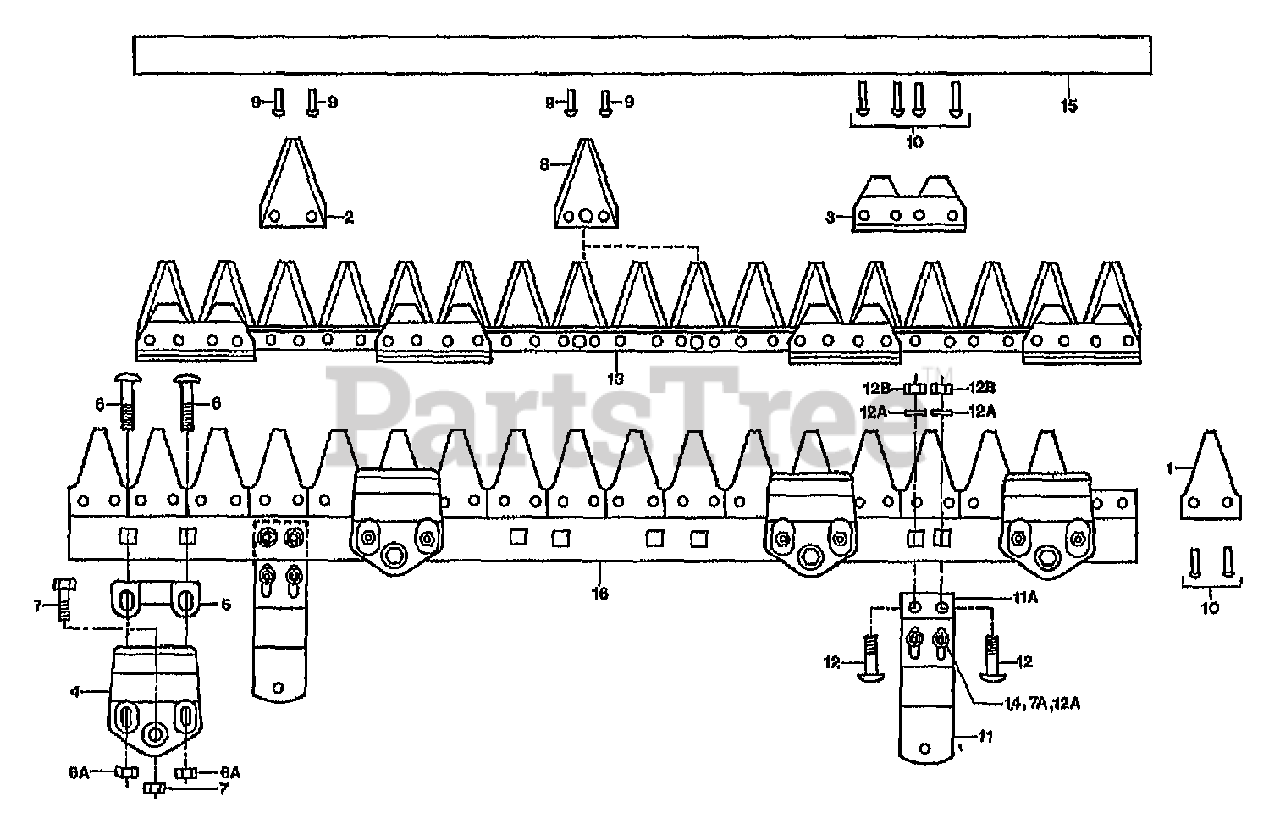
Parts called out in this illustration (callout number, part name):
1	LEDGER SECTION
2	BAR-CUTTER 2 HOLE BLADE SECTIO
3	PLATE-WEAR
4	CLIP-BLADE GUIDE
5	PLATE
6	SCR-CARR M8 X 40
7	SCR-HH M8 X 30
7A	NUT-M8 BRAKE
8	BLADE-SECTIONS 3 HOLES
9	RIVETS-CS90 5.3 X 14
11	BOTTOM HALF - HEIGHT ADJUSTER
11A	TOP HALF - HEIGHT ADJUSTER
12	SCR-CARR M8X30MM SQNK
12A	WASHER-FLAT 5/16 SAE
12B	NUT-NYLOC M8
13	ASSM-34" BLADE T/B SICKLEBAR
14	BOLT-U M8 HEIGHT ADJUST
15	SHIELD-PLASTIC CUTTERBAR
16	LEDGER BAR W/RIVET BLADE
16	KIT-MAINT TRAILBLAZER (INCL. 2,8-10)
